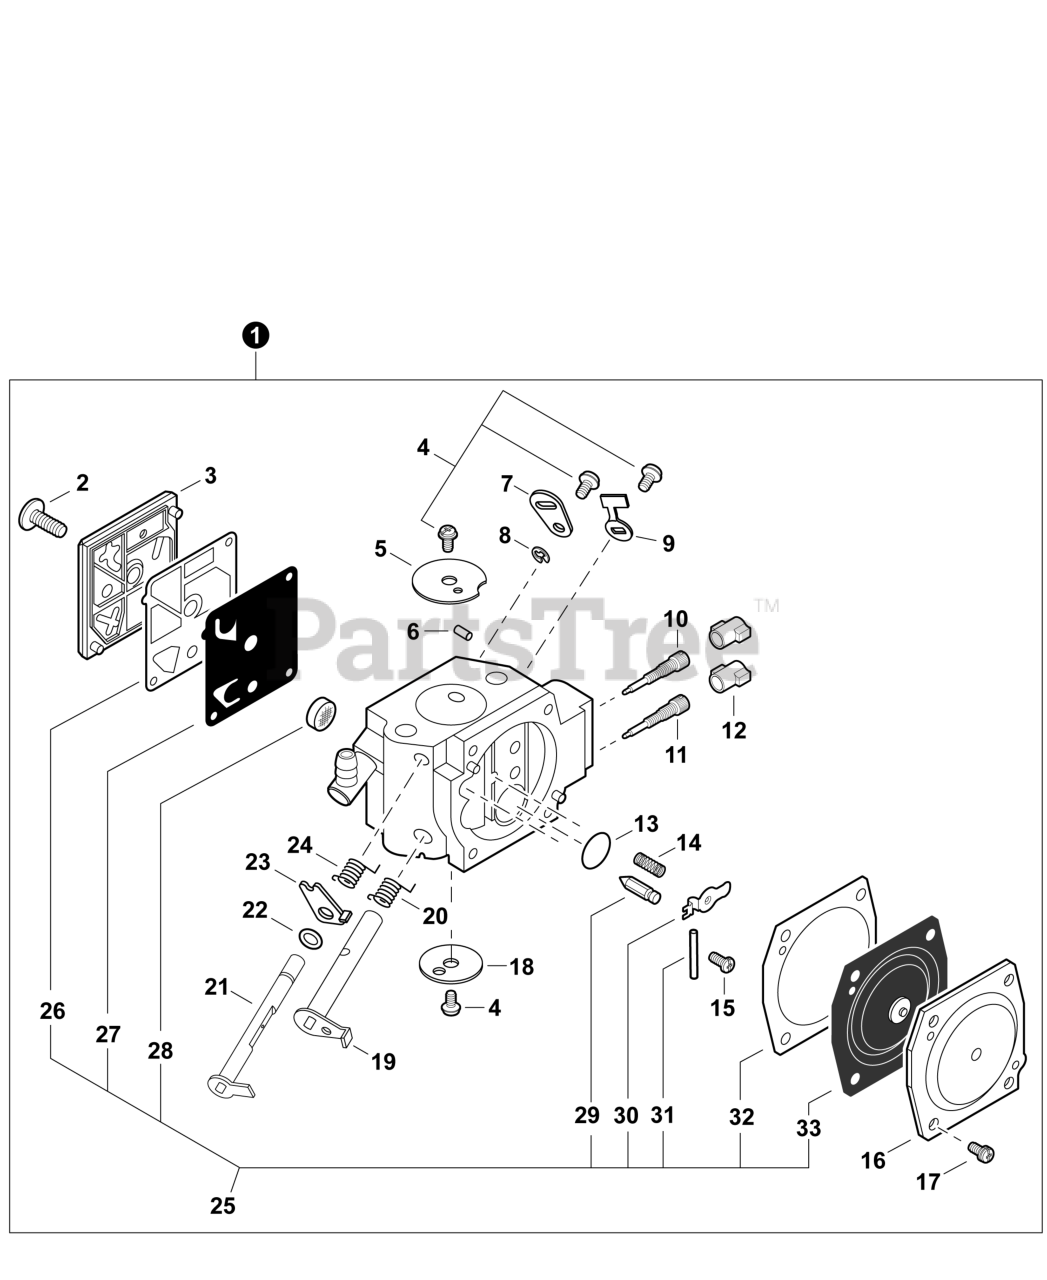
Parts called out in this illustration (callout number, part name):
1	CARBURETOR HDA-324
3	COVER, FUEL PUMP
5	VALVE, CHOKE
6	PLUG, FRICTION
7	LEVER, CHOKE
9	STOP, THROTTLE
10	NEEDLE, HIGH SPEED
11	NEEDLE LOW SPEED
12	CAP, LIMITER
13	PLUG, WELCH
15	SCREW, METERING LEVER PIN
16	COVER, METERING DIAPHRAGM
18	VALVE, THROTTLE
19	SHAFT, THROTTLE
20	SPRING, THROTTLE RETURN
21	SHAFT, CHOKE
23	LEVER, FAST IDLE
24	SPRING, CHOKE RETURN
25	REPAIR KIT
26	GASKET, FUEL PUMP
27	DIAPHRAGM, FUEL PUMP
28	SCREEN, FUEL INLET
29	VALVE, INLET NEEDLE
30	LEVER, METERING
31	PIN, METERING LEVER
32	GASKET, METERING DIAPHRAGM
33	DIAPHRAGM, METERING
